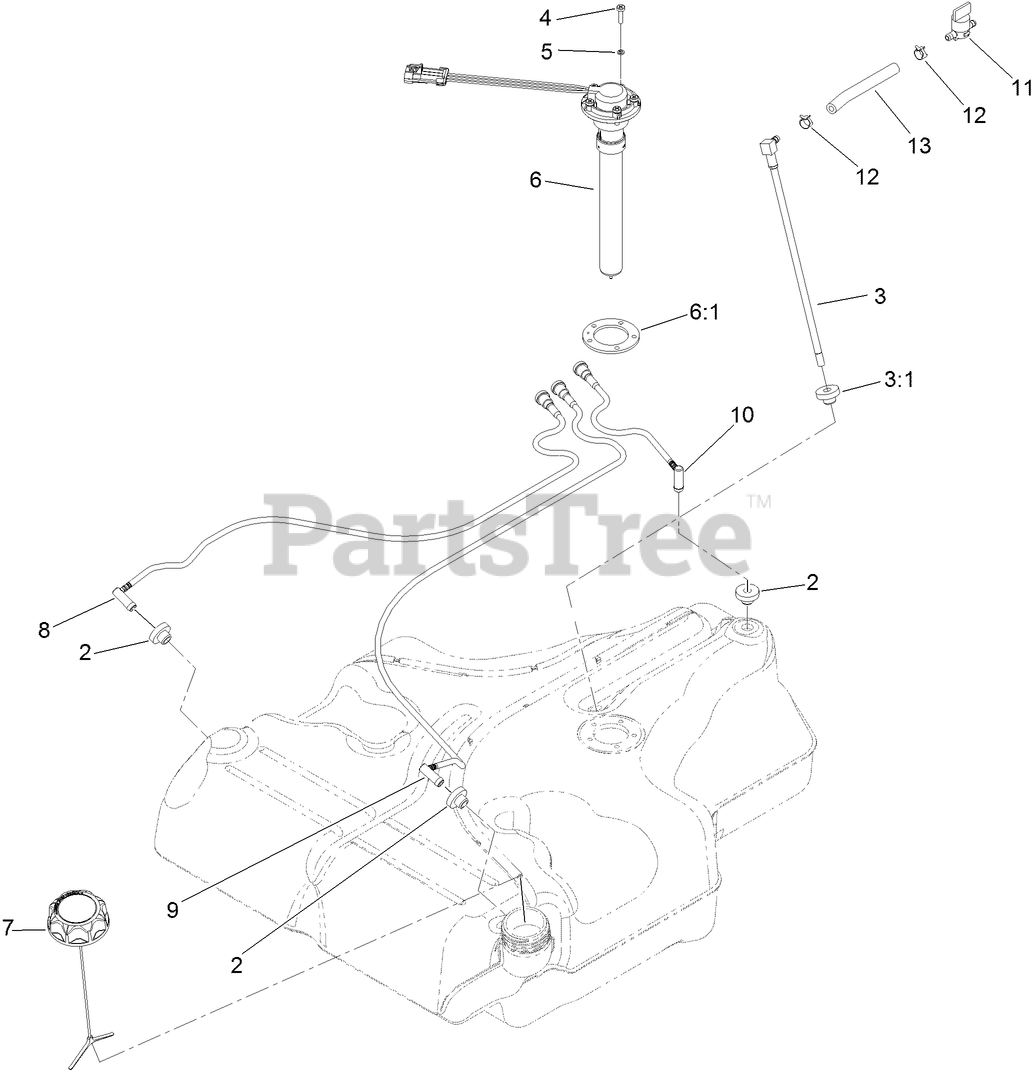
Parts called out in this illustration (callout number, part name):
2	BUSHING
3	FUEL LINE KIT (WITH GROMMET)
3:1	BUSHING
4	SCREW-PAN
5	WASHER-LOCK
6	SENDER-LEVEL, FUEL
6:1	GASKET-SENDER, FUEL
7	CAP-FUEL, RATCHETING
8	RH VENT LINE KIT (WITH GROMMET)
9	LH VENT LINE KIT (WITH GROMMET)
10	REAR VENT LINE KIT (WITH GROMMET)
11	VALVE-FUEL
12	CLAMP-HOSE
13	HOSE-FUEL
